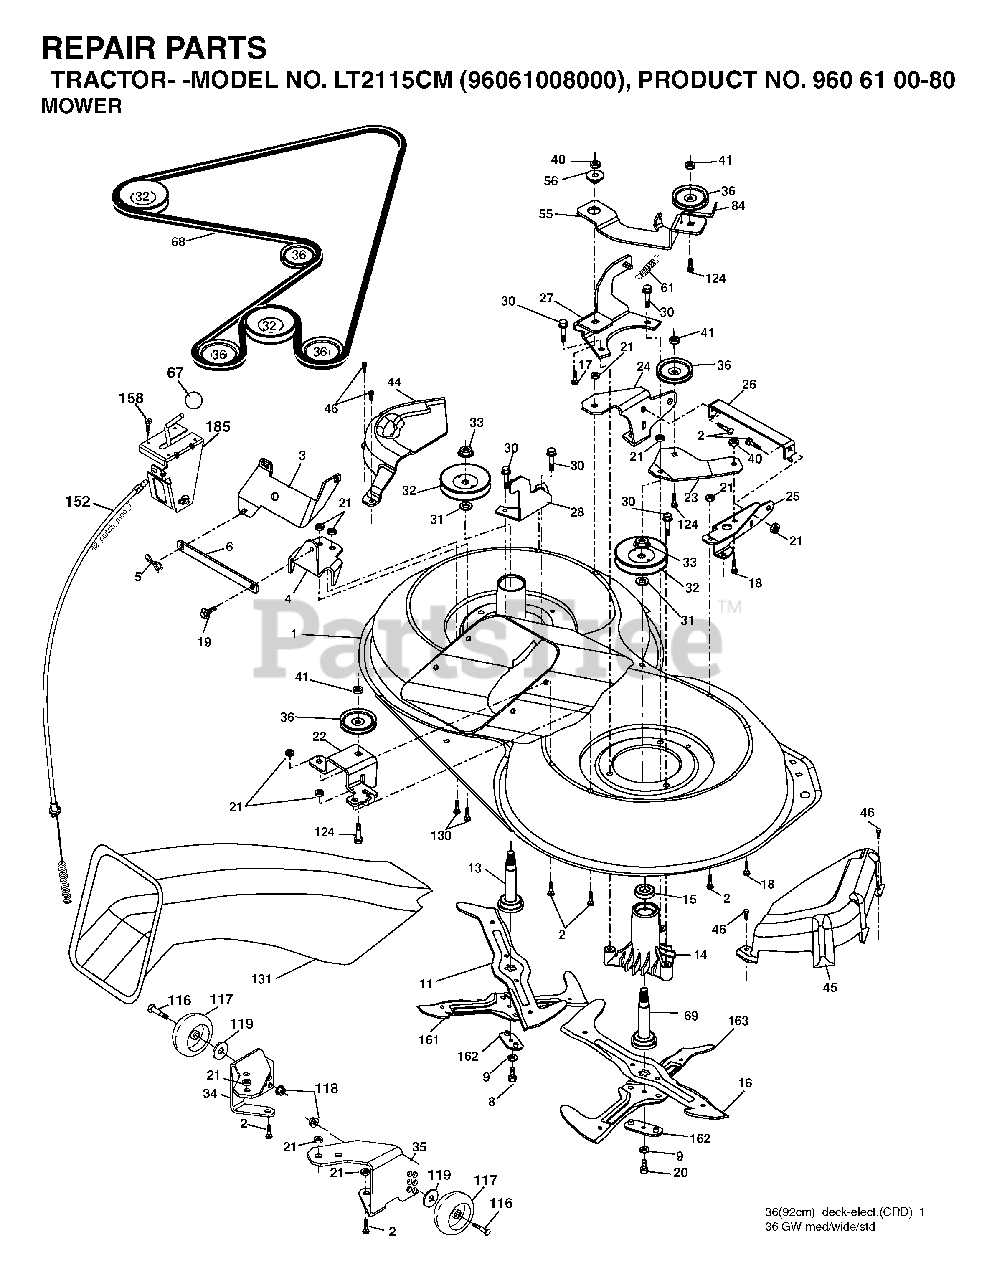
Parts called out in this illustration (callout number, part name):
2	BOLT
3	BRACKET
5	RETAINER-SPRNG RB
6	BAR SWAY
9	LOCKWASHER
13	SHAFT ASM VENT
14	HSG MANDREL
17	BOLT.3/8-14X1.25
19	BOLT SHD 5/16-18
21	LOCKNUT
24	BRACKET
25	BRACKET
28	BRACKET
30	SCREW, WASHER HEAD
31	WASHER.SPACER.MANDREL
32	PULLEY, MANDREL
33	NUT.FLANGE.LOCK.TOP
36	PULLEY.IDLER.4.25
40	LOCKNUT
41	NUT LOCK FLG 3/8-16 UNC
45	MANDREL COVER
46	SCREW.1/4-20X5/8
56	SPACER.RETAINER.MOWER
61	SPRING.TENSION.BELT
67	KNOB T (3/8 HOLE)
69	SHAFT.ASM.W/LWR.BRG.RH.THREAD
84	KEEPER, BELT IDLER
116	SHOULDER BOLT
117	WHEEL. GUAGE RALLY
118	LOCKNUT
119	WASHER
124	BOLT.3/8-16X1.50
131	CHUTE BAGGER
158	SCREW
185	HEAD ASM. CABLE CLUTCH
